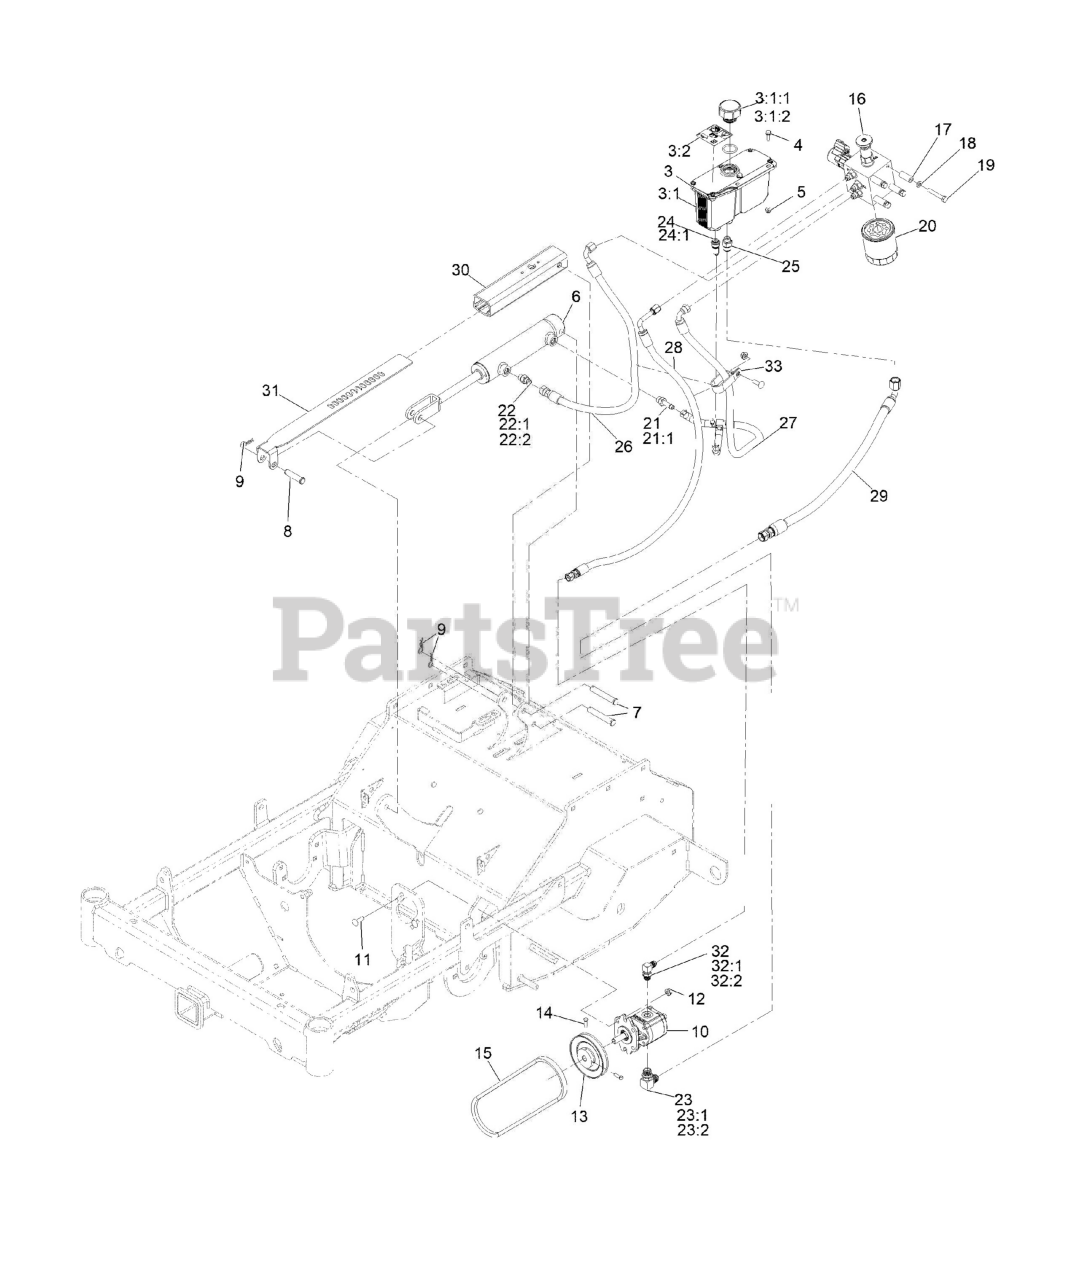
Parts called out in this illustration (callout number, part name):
3	RESERVOIR ASM
3:1	Reservoir-HYD
3:1:1	Cap-Reservoir, HYD
3:2	DECAL-WARNING
4	SCREW-HWH
6	CYLINDER-HYDRAULIC
7	PIN-CLEVIS
8	PIN-CLEVIS
9	PIN-HAIR
10	PUMP-HYDRAULIC
11	SCREW-CARR
12	NUT-HF, NI
14	SCREW-SQH
16	MANIFOLD ASM
18	WASHER-LOCK
19	SCREW-HH
20	FILTER-25 MICRON, BI-DIRECTIONAL
21	ADAPTER-STRAIGHT
21:1	O-RING
22	FITTING-STRAIGHT
22:1	BOSS O-RING
23	FITTING-90 DEG
24	FITTING-BARBED, 45 DEG
24:1	O-RING
25	FITTING-STR
26	HYDRAULIC HOSE ASM
27	HYDRAULIC HOSE ASM
28	HYDRAULIC HOSE ASM
29	HYDRAULIC HOSE ASM
30	HOUSING-DEPTH CONTROL
31	BRACKET-DEPTH CONTROL
32	FITTING-90 DEG
32:1	BOSS O-RING
33	Clamp-R, Double
